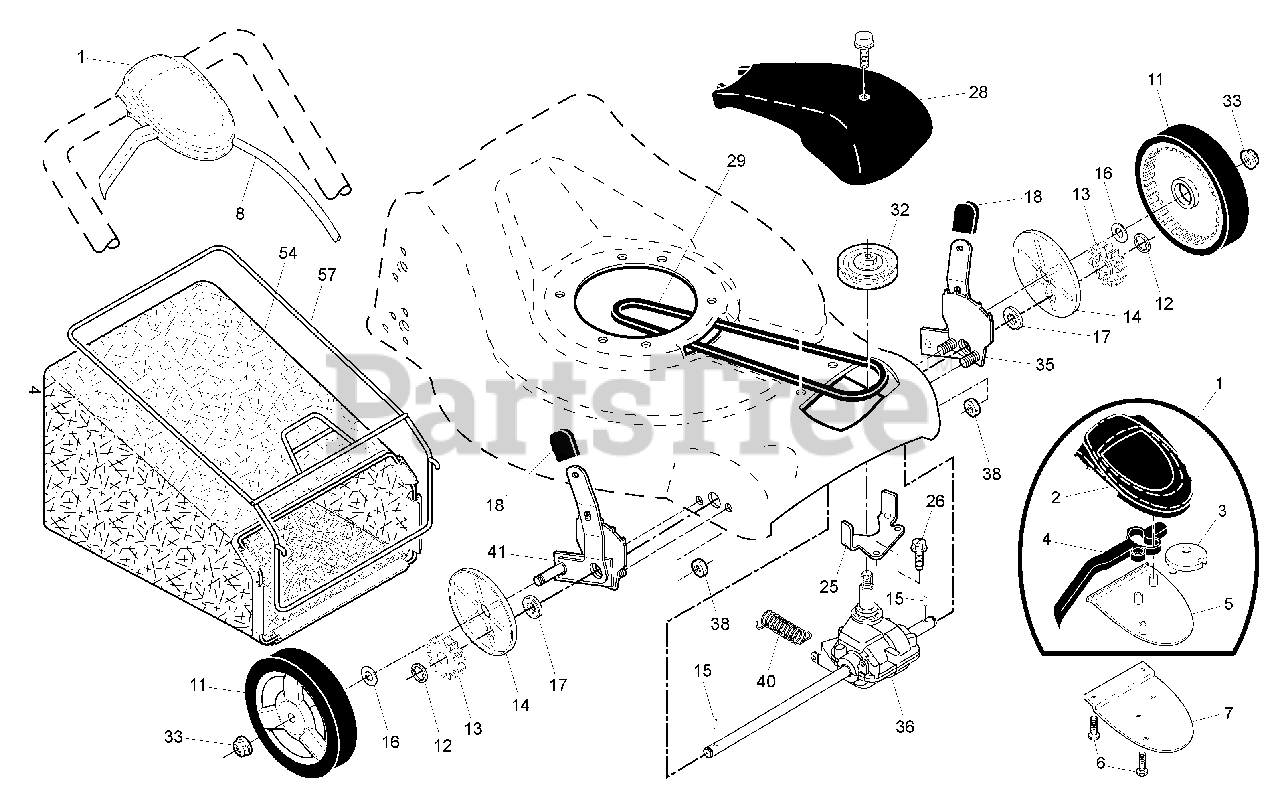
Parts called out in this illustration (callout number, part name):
1	Drive Control Assembly
2	Cover, Drive Control, Upper
4	Lever, Drive Control
5	Cover, Drive Control, Lower
7	Mounting Bracket, Drive Control
8	Cable, Drive Control
11	Wheel & Tire Assembly
14	Dust Cover
15	Pawl, Drive
16	Washer 1/2 x 1-1/2 x .134
17	Bearing, Wheel Adjuster
18	Selector Knob
25	Belt Keeper
26	Screw, Hi-Lo Thread #12 x 5/8
28	Drive Cover Assembly
32	Pulley, Drive
33	Locknut, Hex
35	Kit, Wheel Adjuster, LH
36	Gear Case Assembly, Complete
38	Locknut 1/4-20
41	Kit, Wheel Adjuster, RH
54	Grassbag Assembly
57	Frame, Grassbag
